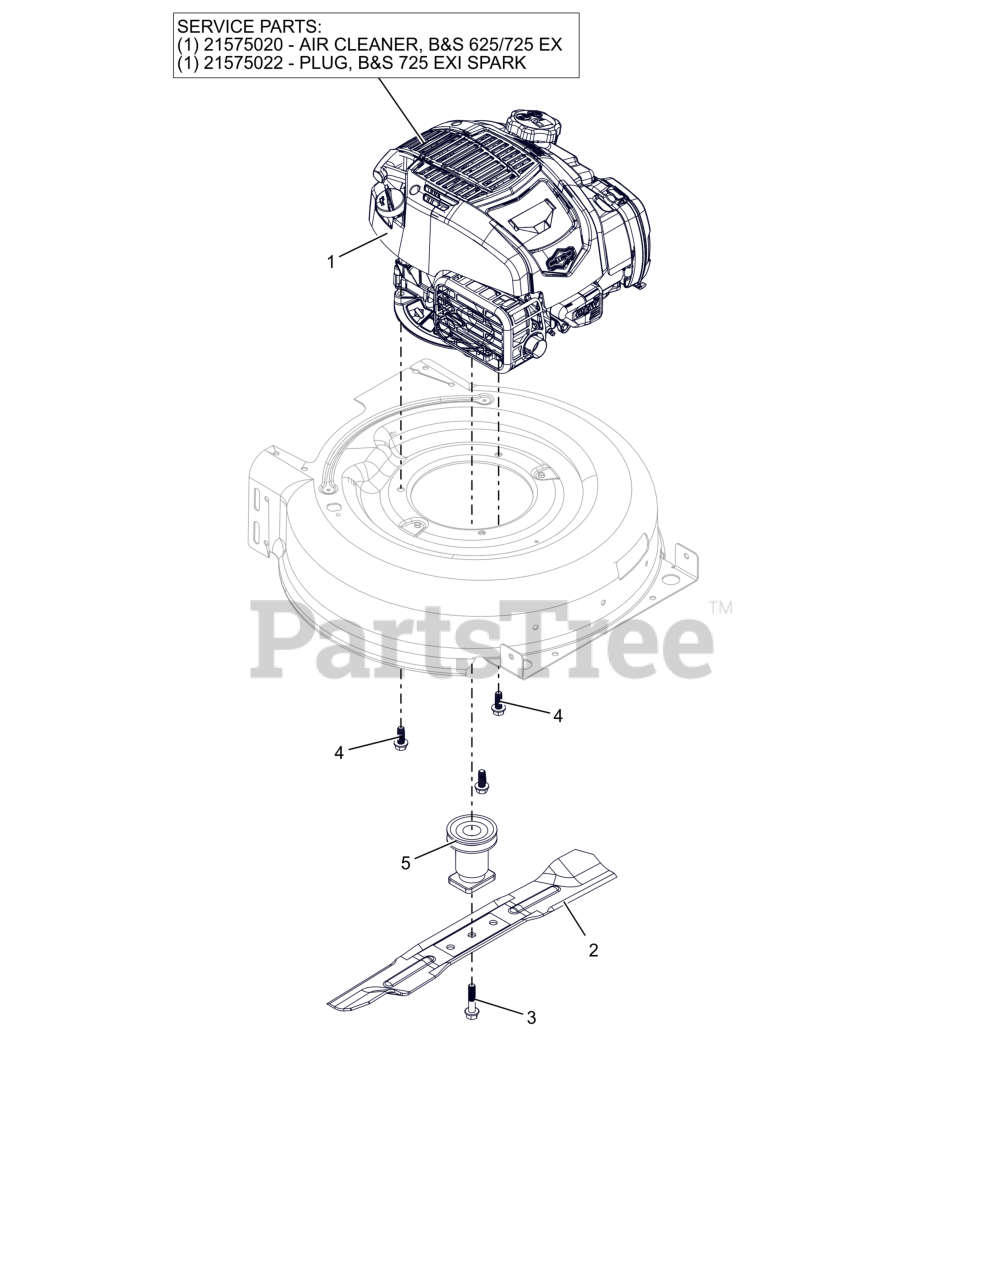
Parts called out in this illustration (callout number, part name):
1	ENGINE, BRIGGS 725 EXI
1	AIR CLEANER- B&S 625/725 EX
1	PLUG- B&S 725 EXI SPARK
2	BLADE, MOWER 21" HIGH LIFT
3	SCR, HEX FLANGE 3/8-24X1.75
4	SCR-TAP, 3/8-16X1.00 HWH
5	SPCR, BLADE - SINGLE
